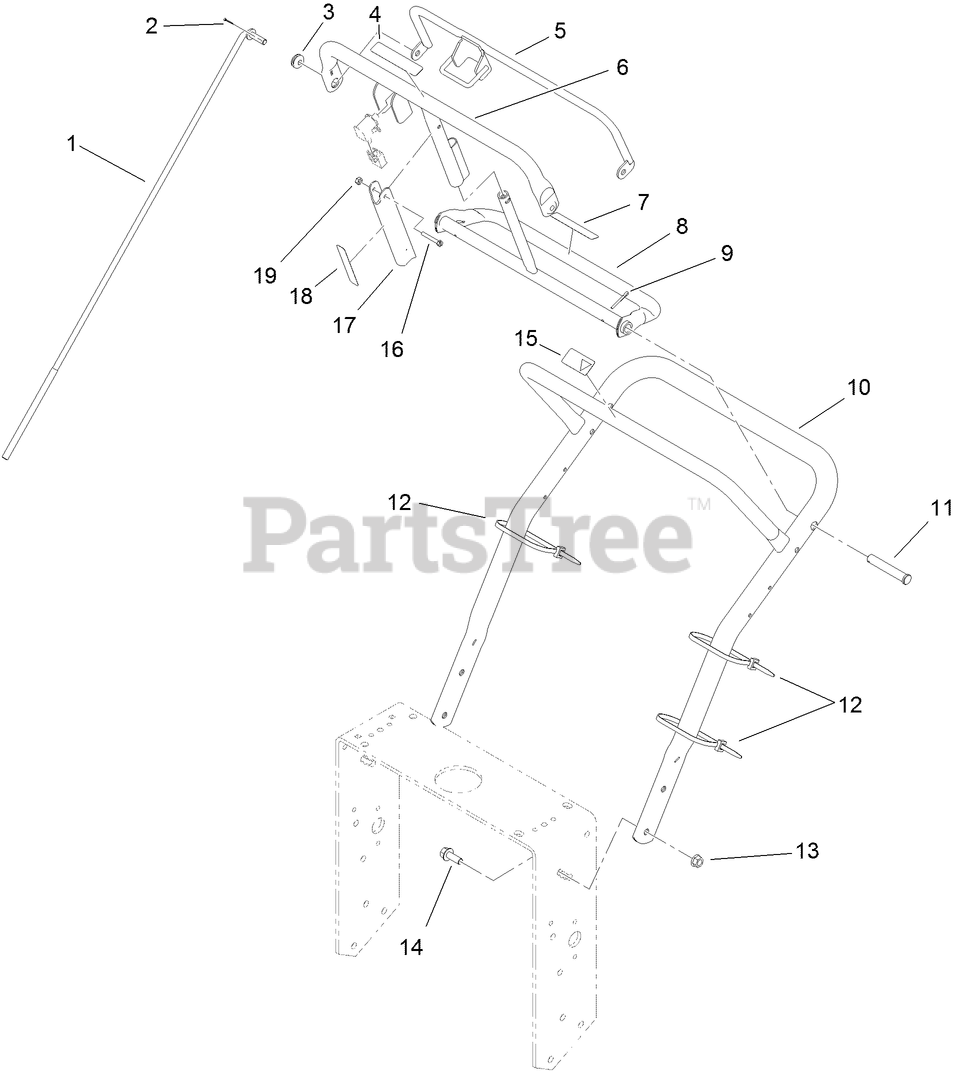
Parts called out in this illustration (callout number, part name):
1	ROD-CONTROL
2	SCREW-HH
3	GROMMET-RUBBER
4	DECAL-BAR, CONTROL
6	BAR-CONTROL
7	DECAL-REVERSE
8	PIVOT-CONTROL
9	PIN-COTTER
11	PIN-CLEVIS
12	TIE-CABLE
13	NUT-HF
14	SCREW-HHF
15	DECAL-PROTECTION, EAR
16	SCREW-SHH
17	LEVER-BRAKE, PARKING
18	DECAL-LEVER, PARKING
19	NUT-LOCK, NI
